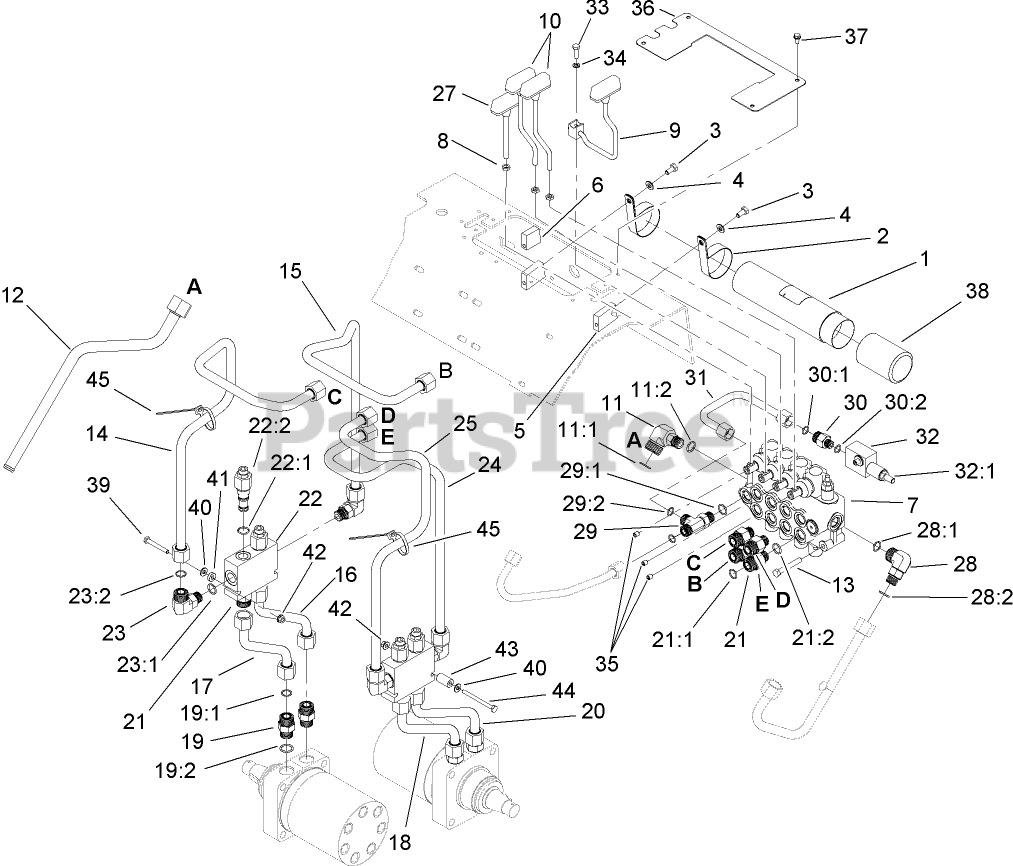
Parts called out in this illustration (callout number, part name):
1	TUBE-MANUAL
2	CLAMP-R
3	SCREW-HH
4	WASHER-PLAIN
5	SPACER
6	SPACER-UPPER
7	VALVE-FOUR SPOOL (W/ RELIEF PORT)
8	NUT-HEX
9	LEVER-CONTROL
10	LEVER-DRIVE
11	FITTING-HYD, 90 DEG
11:1	O-RING
11:2	O-RING
12	TUBE-TANK, HYD
13	SCREW-HH
14	TUBE-HYD (RIGHT B)
15	TUBE-HYD (RIGHT A)
16	TUBE-HYD
17	TUBE-HYD
18	TUBE-HYD
19	FITTING-STRAIGHT
19:1	O-RING
19:2	O-RING
20	TUBE-HYD
21	FITTING-STR
21:1	O-RING
21:2	O-RING
22	VALVE-COUNTERBALANCE
22:1	SEAL KIT
22:2	VALVE-CARTRIDGE
23	Fitting-Elbow, 90 DEG
23:1	O-RING
23:2	O-RING
24	TUBE-HYD (LEFT A)
25	TUBE-HYD (LEFT B)
27	LEVER-CYLINDER
28	Fitting-Elbow, 90 DEG
28:1	O-RING
28:2	O-RING
29	FITTING-TEE
29:1	O-RING
29:2	O-RING
30	FITTING-STR
30:1	O-RING
30:2	O-RING
31	TUBE-HYD
32	RELIEF VALVE ASM
32:1	CARTRIDGE-VALVE, RELIEF
33	SCREW-HH
34	WASHER-LOCK
35	SCREW-SET, HSH
36	PLATE-COVER
37	SCREW-HWH
38	CAP-HOUSING
39	SCREW-HH
40	WASHER-FLAT
41	SPACER
42	NUT-HHF
43	SPACER
44	SCREW-HH
45	TIE-CABLE
